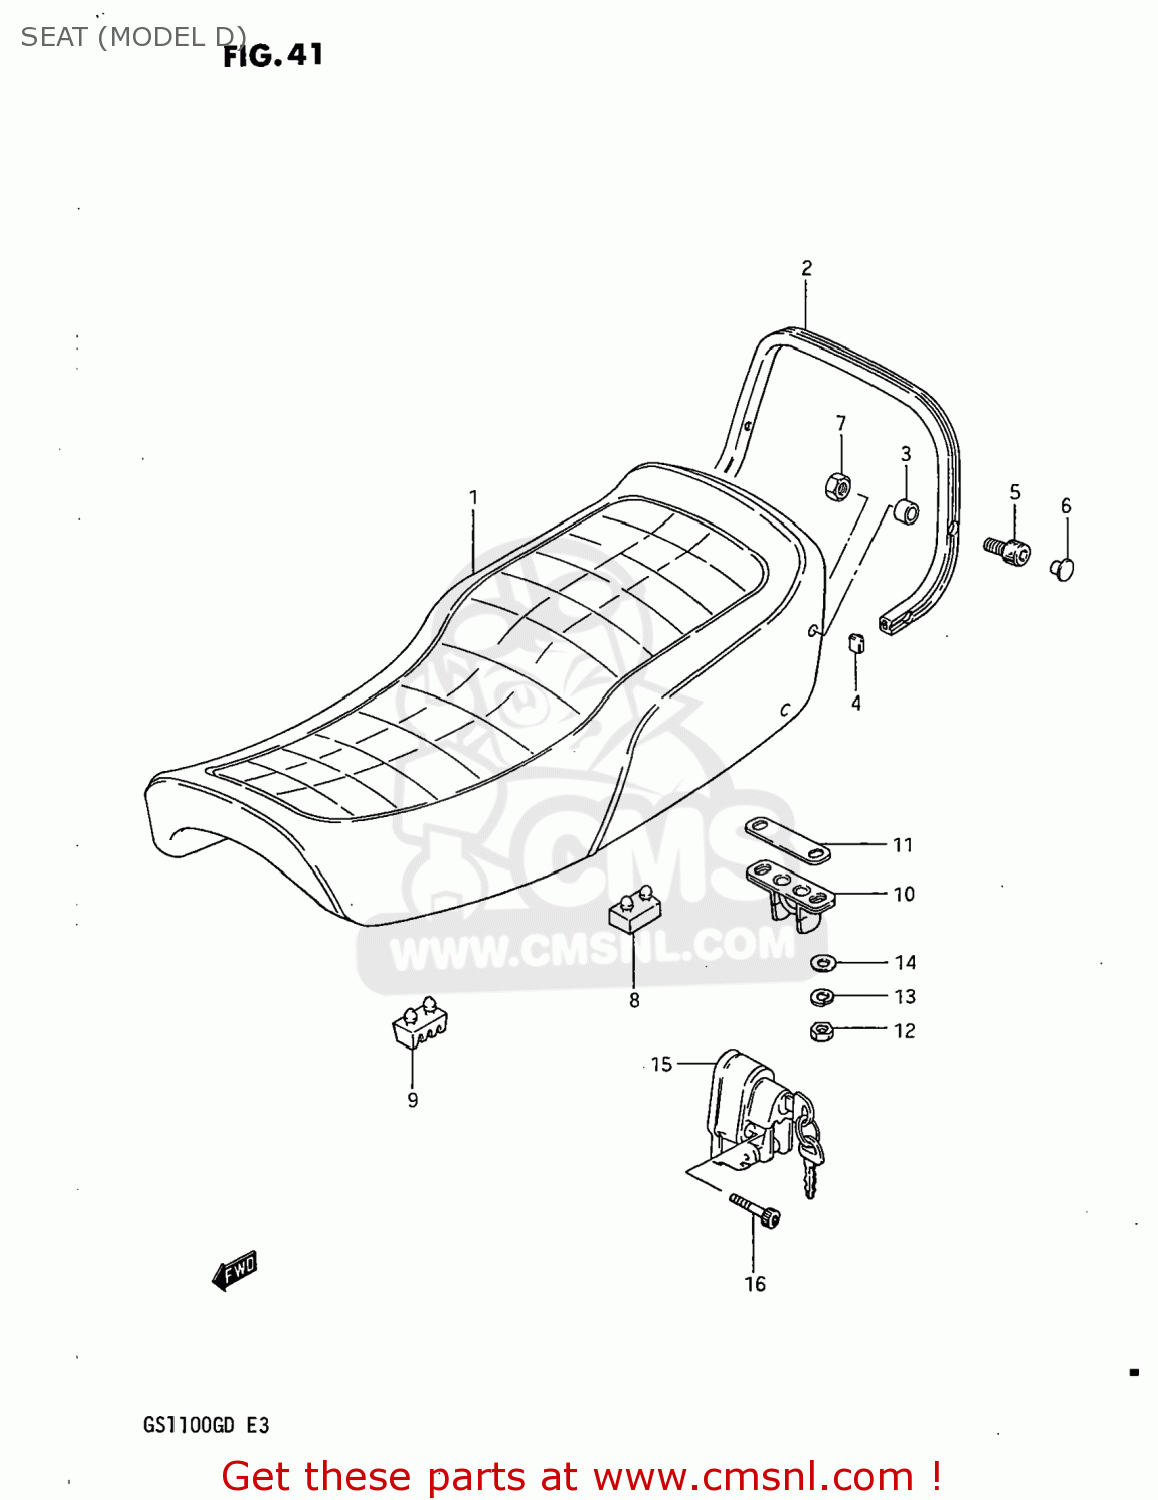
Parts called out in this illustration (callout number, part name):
1	SEAT ASSEMBLY
2	HANDLE,PILLION RIDER
3	SPACER,REAR
4	END,PILLION RIDER HAND
5	BOLT
6	CAP(OD:14.5)
7	NUT
8	CUSHION
9	CUSHION,SUPPORT(50X25X32)
10	STRIKER,SEAT LOCK
11	SHIM,SEAT LOCK STRIKER
12	NUT 6MM
13	LOCK WASHER
14	WASHER
15	LOCK ASSY,HELMET
16	BOLT 5X25
